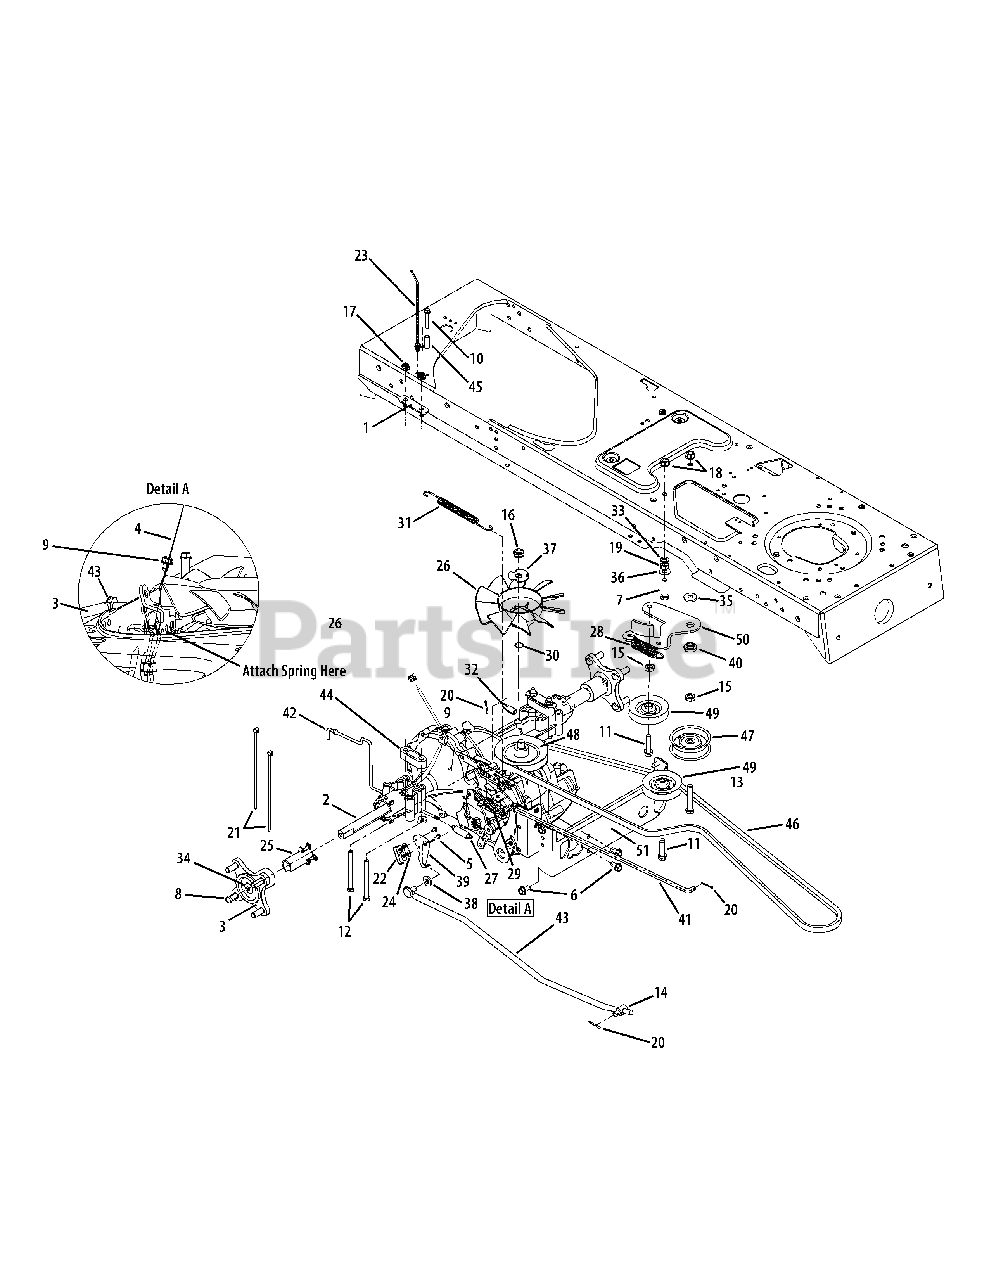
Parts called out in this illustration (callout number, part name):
2	Transmission, Hydrostatic
3	Hub Assembly, Wheel
4	Harness Assembly, Grnd. & Rev.
5	Screw, #8-18, 0.500
6	Screw, 5/16-12, 0.75
7	Hex Cap Screw, 3/8-16, 1.50, Gr5
8	Hex Cap Screw, 5/16-24 x .750
9	Screw, 1/4-20 x .375
10	Hex Cap Screw, 1/4-20, 1.5, Gr5
11	Screw, 3/8-16, x 1.50
12	Hex Cap Screw, 5/16-18,3.5, Gr5
13	Hex Cap Screw, 3/8-16, 2.25, Gr5
14	Ferrule, 3/8-24 x .375 Dia
15	Nut, Jam, 7/16-20, Gr2
16	Nut, Jam Lock, 1/2-20, Gr5
17	Nut, Hex Nylon Lock, 5/16-18
18	Nut, Flange Lock, 3/8-16
19	Nut, Hex, 3/8-16, Gr8
20	Pin, Cotter, 3/32, 1.0
21	Cable, Tie, 3/16 x .05 x 7.4
22	Switch, Spring, Short
23	Tie, Cable, Push Mount 7.5 Lg
24	Plate, Insulator Nut
25	Sleeve, 2.4"
26	Fan, Blade
27	Spring, .48 OD x 2.03 Extension
28	Spring, Extension, .563 Dia x 3.72 Lg
29	Spring, Extension, .59 OD x 4.00 Lg
30	Ring, Wire
31	Spring, Extension, .500 Dia x 7.0
32	Spring, Extension, 3/8 OD x 1.44
33	Washer, Lock, 3/8, Regular Duty
34	Bell Washer
35	Washer, Flat, .385 x 1.0 x .135
36	Washer, Flat, .406 x .875 x .059
37	Washer, Lock, Hydro
38	Washer, Flat, .407 x .812 x .135
39	Bracket, Actuator, Switch
40	Spacer, Shoulder, 1.00 x .38 x .38
41	Rod, Brake, Hydro
42	Rod, Hydro Bypass
43	Rod, Control, Hydro
44	Spacer, T-axle .68
45	Spacer, 1"
46	Belt, V Type, Poly
47	Pulley, Idler, Flat 2.75 OD
48	Pulley, Engine, 4.13 Dia.
49	Pulley, Idler, V Type x 3.06 Dia
